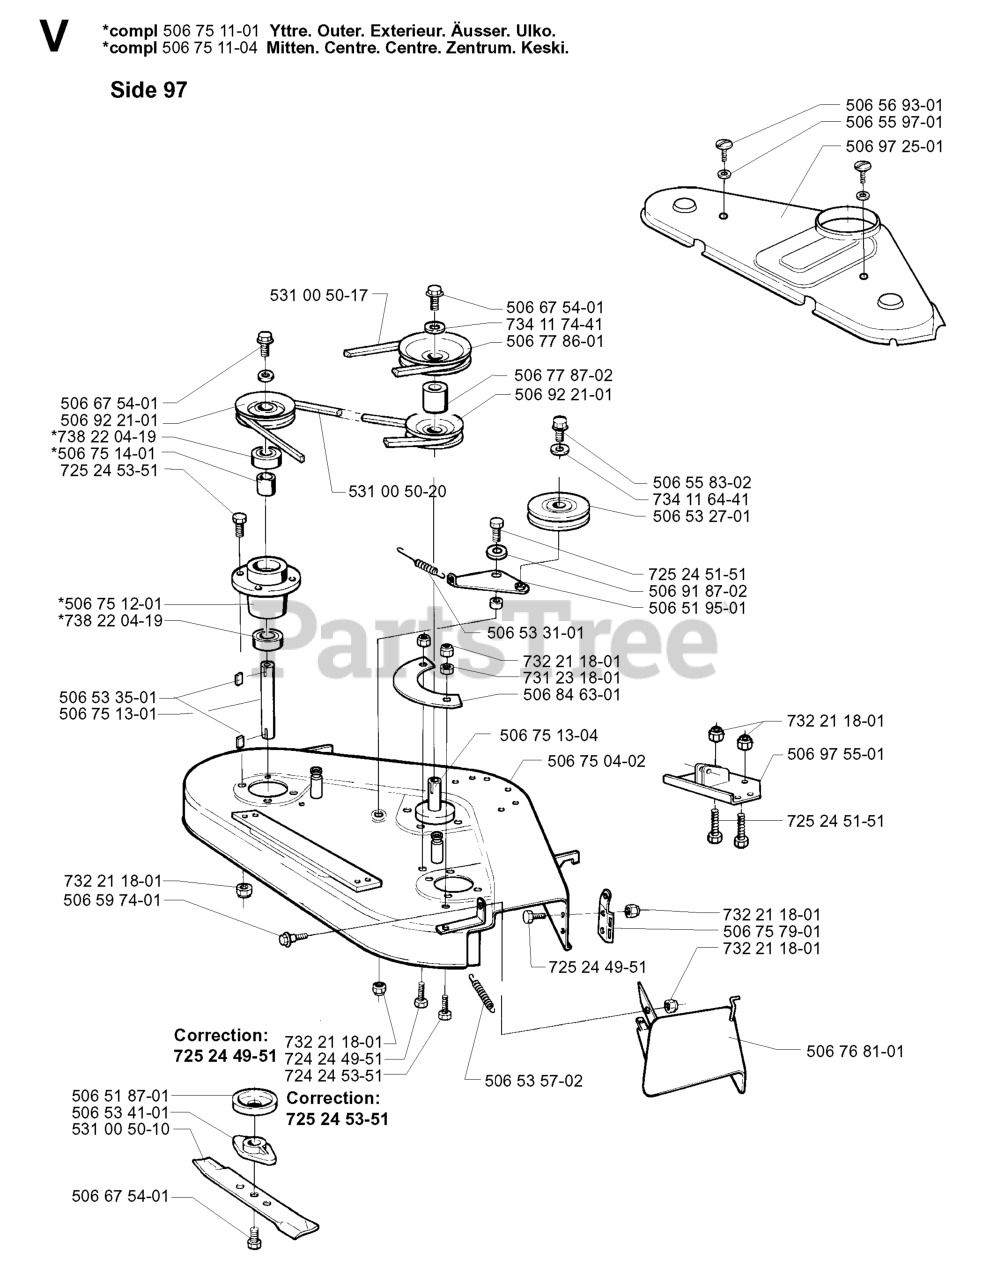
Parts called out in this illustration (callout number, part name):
1	CONTROL.THROTTLE/CHOKE.BLACK
2	SCREW
4	MUFFLER.LT.BRIGGS.14HP.IC/OHV
13	REPL BY 532 27 22-93
14	TUBE, DRAIN OIL ASM.
16	LOCKWASHER
23	SHIELD.BROWNING.DBR.GUARD
29	KIT.SPARK ARRESTOR 794945 B&S
31	TANK.ASM.FUEL.FRONT.W/CAP
32	FUEL CAP
33	HOSE CLAMP
37	LINE.FUEL.20
38	PLUG DRAIN OIL EASY
40	BUSHING.SNAP.NYL.BLK.
44	SCREW HEXWSHR 1/4-20X3/4
45	SCREW, 3/8-16X3/4
72	SCREW.SOCKET.HEAD.5/16-18
78	SCREW.3/8-16
81	NUT
